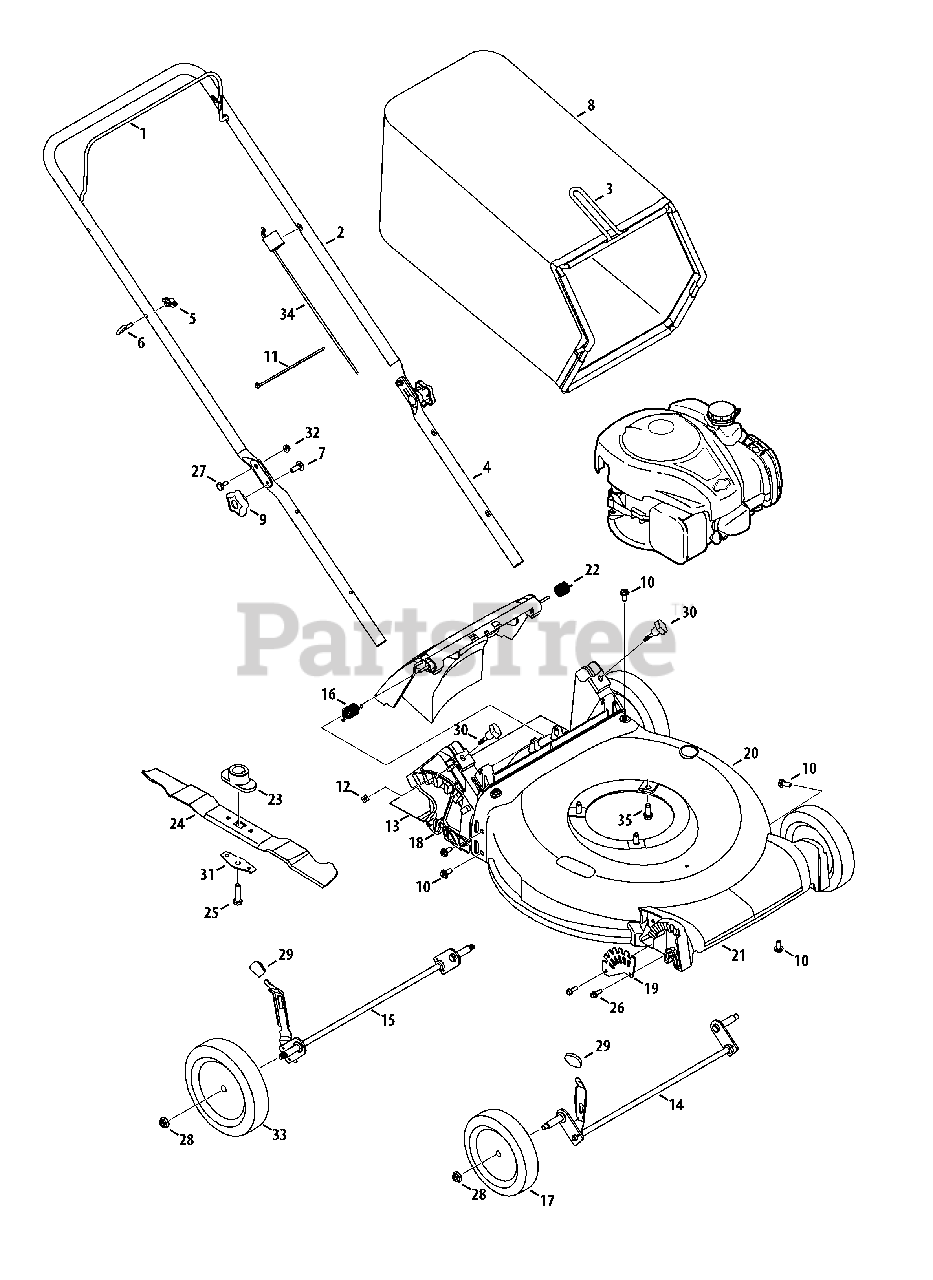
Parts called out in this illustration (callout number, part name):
1	Blade Control
2	Upper Handle
4	Lower Handle
5	Wing Nut
6	Rope Guide
7	Carriage Screw ,5/16-18
8	Grass Bag
9	Hand Knob
10	Screw, 5/16-14 x .750
11	Cable Tie
12	Nut, Sq., 1/4-20
13	Trail shield
14	Front Axle Assembly
15	Rear Axle Assembly
16	Torsion Spring - RH
17	Wheel, 7 x 1.8
18	Rear Discharge Assembly
19	Front Height Adjuster Plate
20	Deck - 21"
21	Front Cover
22	Torsion Spring - LH
23	Blade Adapter
24	Mulching Blade
25	Screw , 3/8-24 x 1.50
26	Screw, 1/4-15 x .750
27	Sldr. Screw, .375 x .126 x 1/4-20
28	Flange Lock Nut, 3/8-16
29	Adjustment Lever Knob
30	Wing Nut
31	Blade Bell Support
32	Nut, Flange Lock, 1/4-20
33	Wheel, 8 x 1.8
34	Control Cable
35	TT Sems Screw, 3/8-16 x 1.0
